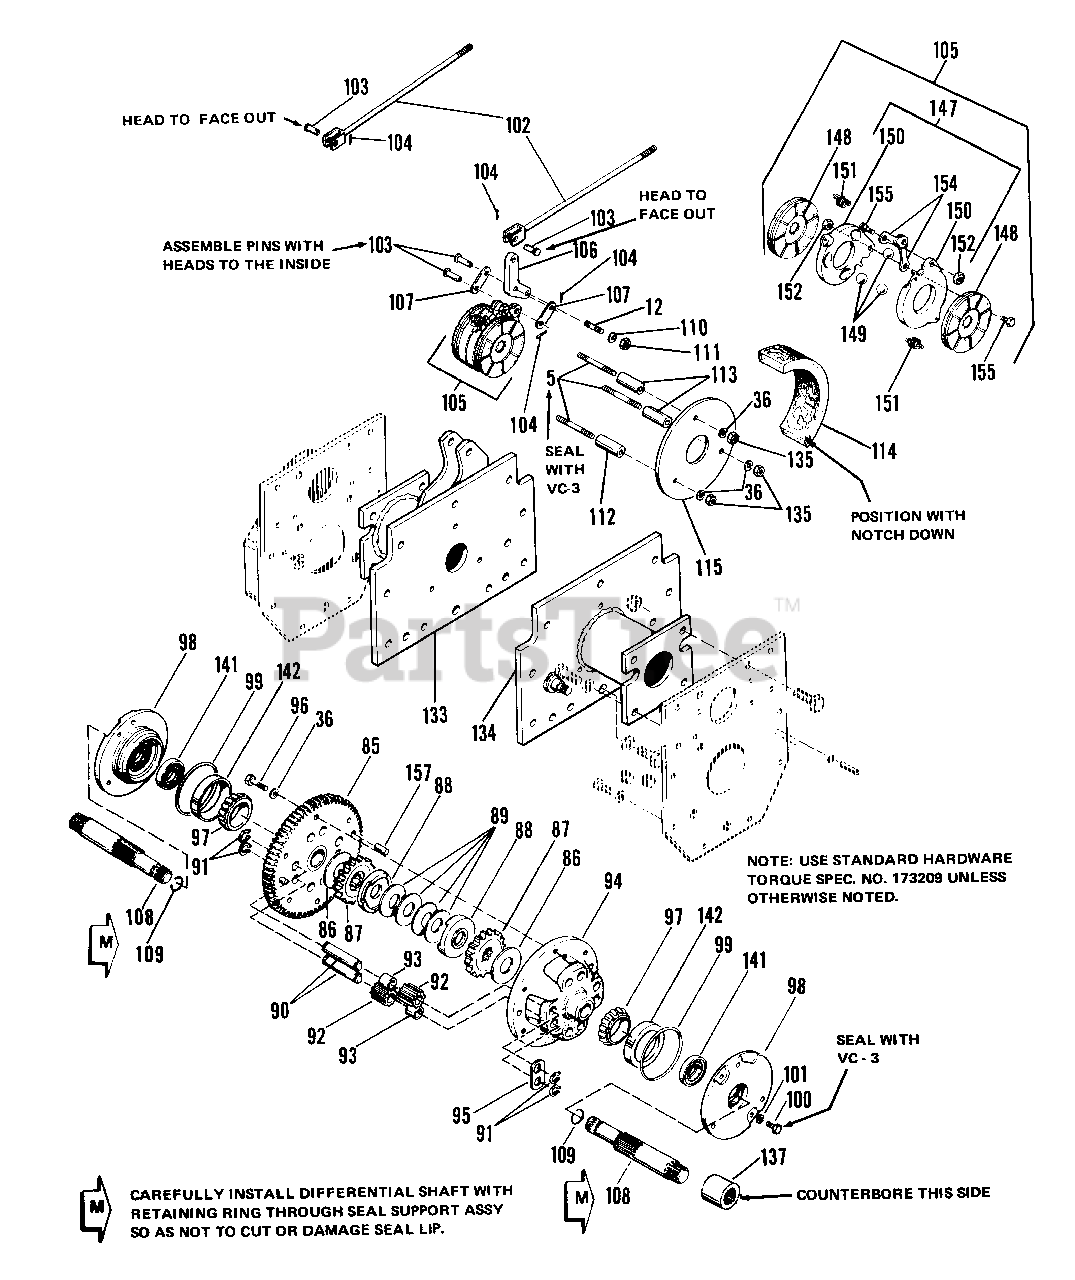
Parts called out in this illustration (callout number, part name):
36	LOCKWASHER, 3/8
85	GEAR ASSY, Differential
86	WASHER, Thrust
87	GEAR, Differential
88	CLUTCH, Differential
89	WASHER, Spring
90	SHAFT, Pinion
91	RING, Retaining
92	GEAR, Pinion
94	CARRIER, Gear
95	PLATE, Locking
96	CAPSCREW: Hex, 3/8-16 x 1-1/4
97	BEARING, Cup
98	SUPPORT ASSY
100	CAPSCREW, Hex, 5/16-18 x 3/4
101	LOCKWASHER, 5/16
102	ROD ASSY, Brake
104	PIN, Cotter, 3/4 x 3/32
105	BRAKE ASSY, Disc.
106	LEVER, Brake
107	PLATE, Link
108	SHAFT, Differential
109	RING, Retaining
111	NUT, Hex, Lock, Jam, 3/8-16
115	PLATE, Shim
133	AXLE EXTENSION ASSY, L.H.
134	AXLE EXTENSION ASSY, R.H.
135	NUT, Hex, 3/8-16
137	COUPLING, Axle
141	SEAL, Brake
142	BEARING, Cone
147	ACTUACTING DISC ASSY
148	MIDDLE DISC ASSY
150	DISC., Actuating
152	NUT, Hex, Jam
154	LINK, Actuating
157	PIN, Dowel
